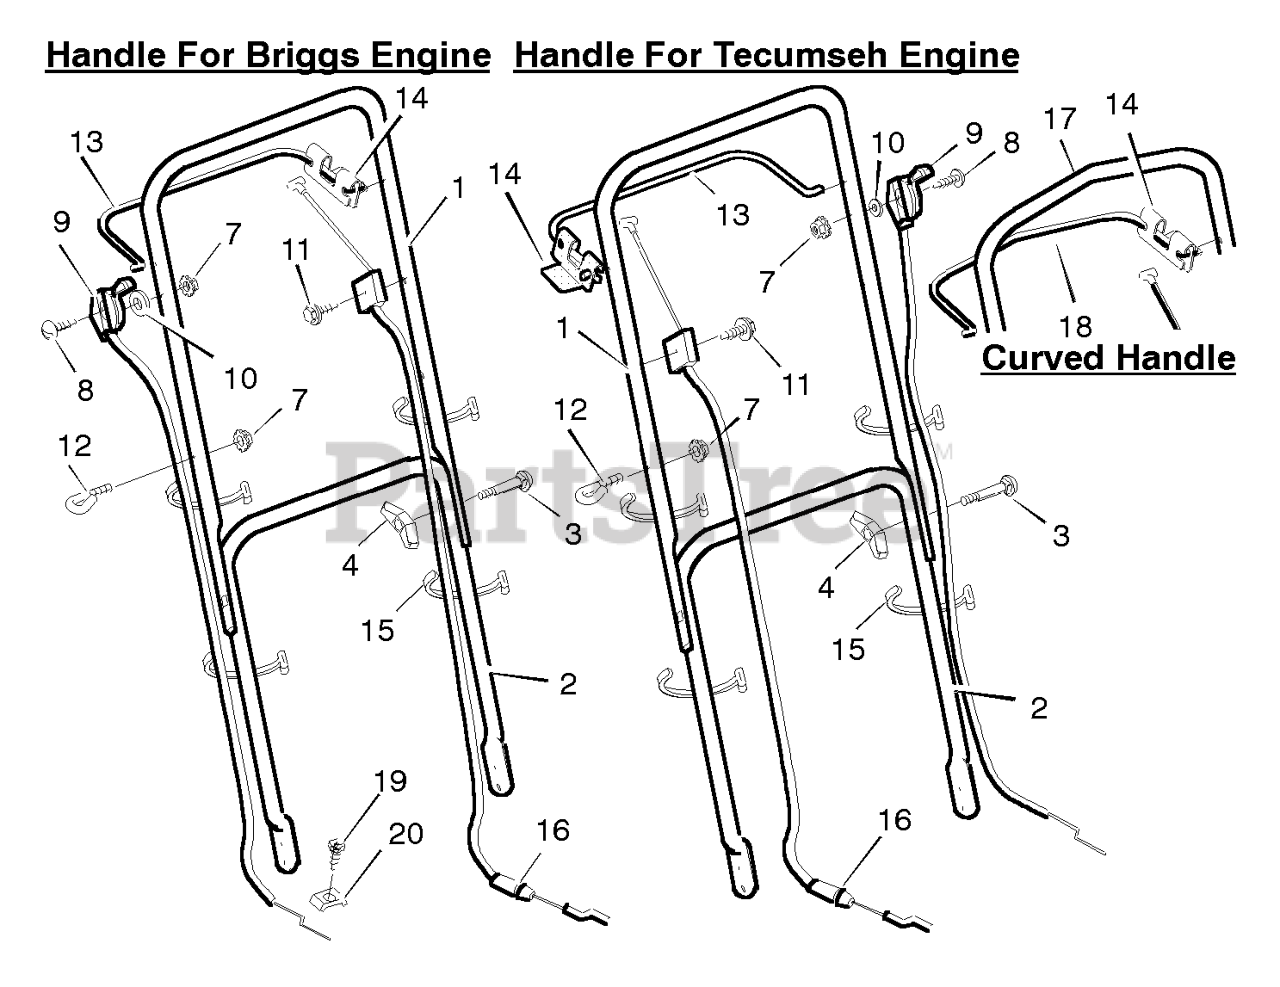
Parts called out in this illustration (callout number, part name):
1	Handle, Upper-Straight (Black)
2	Handle, Lower (Black)
4	Knob, Plastic
7	Locknut
9	Throttle Control
10	Washer
12	GUIDE, ROPE
13	Stop Lever - Straight
14	Bracket, Stop Lever
15	Fastener, Cable
16	Engine Stop Cable *
17	Handle, Upper- Curved (Black)
18	Stop Lever - Curved
19	Screw *
20	Clamp
